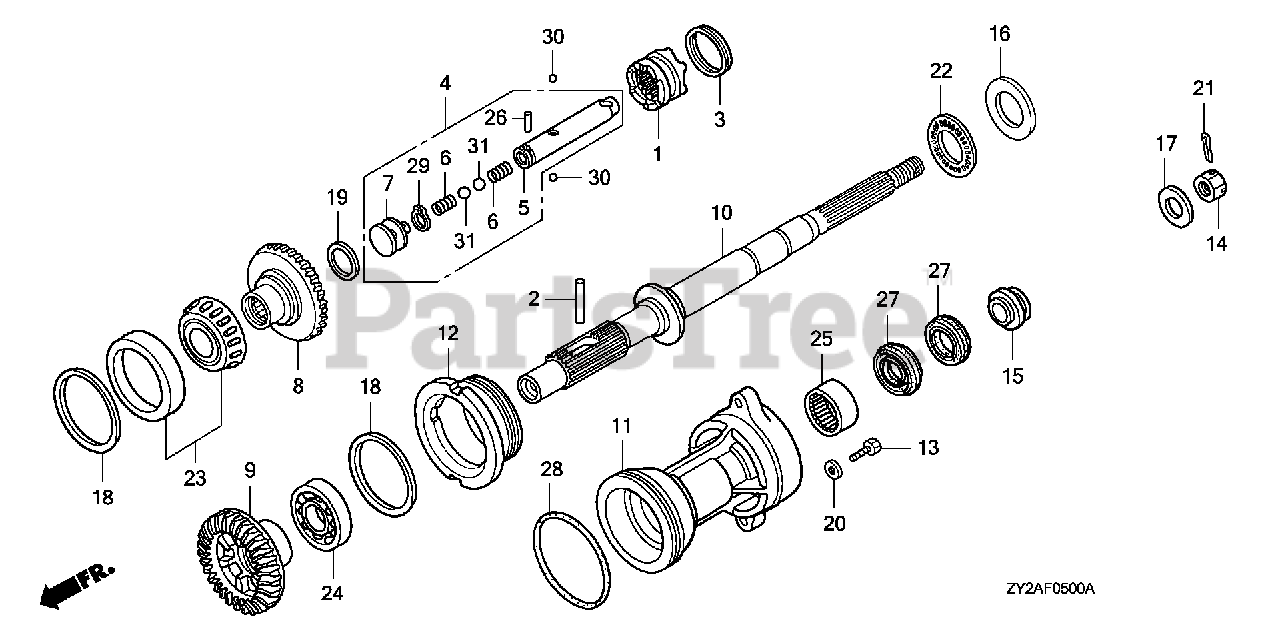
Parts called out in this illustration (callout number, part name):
1	SHIFTER, CLUTCH
2	PIN, SHIFTER (8X50)
3	RING, CROSS PIN
4	SLIDER, SHIFT
5	SLIDER, SHIFT
6	SPRING, SHIFT
7	PLATE, SHIFT
8	GEAR, FR. BEVEL (28T)
9	GEAR, BEVEL (RVS. 28T)
10	SHAFT, PROPELLER
11	HOLDER, PROPELLER SHAFT *NH282MU* (OYSTER SILVER METALLIC-U)
12	HOLDER, BEARING
13	BOLT, HEX. (12X45)
14	NUT, CASTLE (18MM)
15	WASHER, PROPELLER THRUST
16	WASHER, THRUST BEARING
17	WASHER, PROPELLER
18	SHIM A, BEVEL (0.10)
18	SHIM B, BEVEL (0.15)
18	SHIM C, BEVEL (0.30)
18	SHIM D, BEVEL (0.50)
19	SHIM C, THRUST (2.85)
19	SHIM D, THRUST (2.90)
19	SHIM E, THRUST (2.95)
19	SHIM F, THRUST (3.00)
19	SHIM G, THRUST (3.05)
19	SHIM H, THRUST (3.10)
19	SHIM A, THRUST (2.75)
19	SHIM B, THRUST (2.80)
19	SHIM I, THRUST (2.70)
20	WASHER, PLAIN (12MM)
21	PIN, SPLIT (4.0)
22	BEARING, THRUST (F)
23	BEARING, TAPER (50X90X21.5)
24	BEARING, ANGULAR (50X90X30.2)
25	BEARING, NEEDLE (32X42X30)
26	ROLLER (4X13.8)
26	ROLLER (3X13.8)
27	SEAL, WATER (30X45X7)
28	O-RING (105X3.1)
29	CIRCLIP (OUTER) (15MM)
30	BALL, STEEL (#7) (7/32)
31	BALL, STEEL (#12) (3/8)
